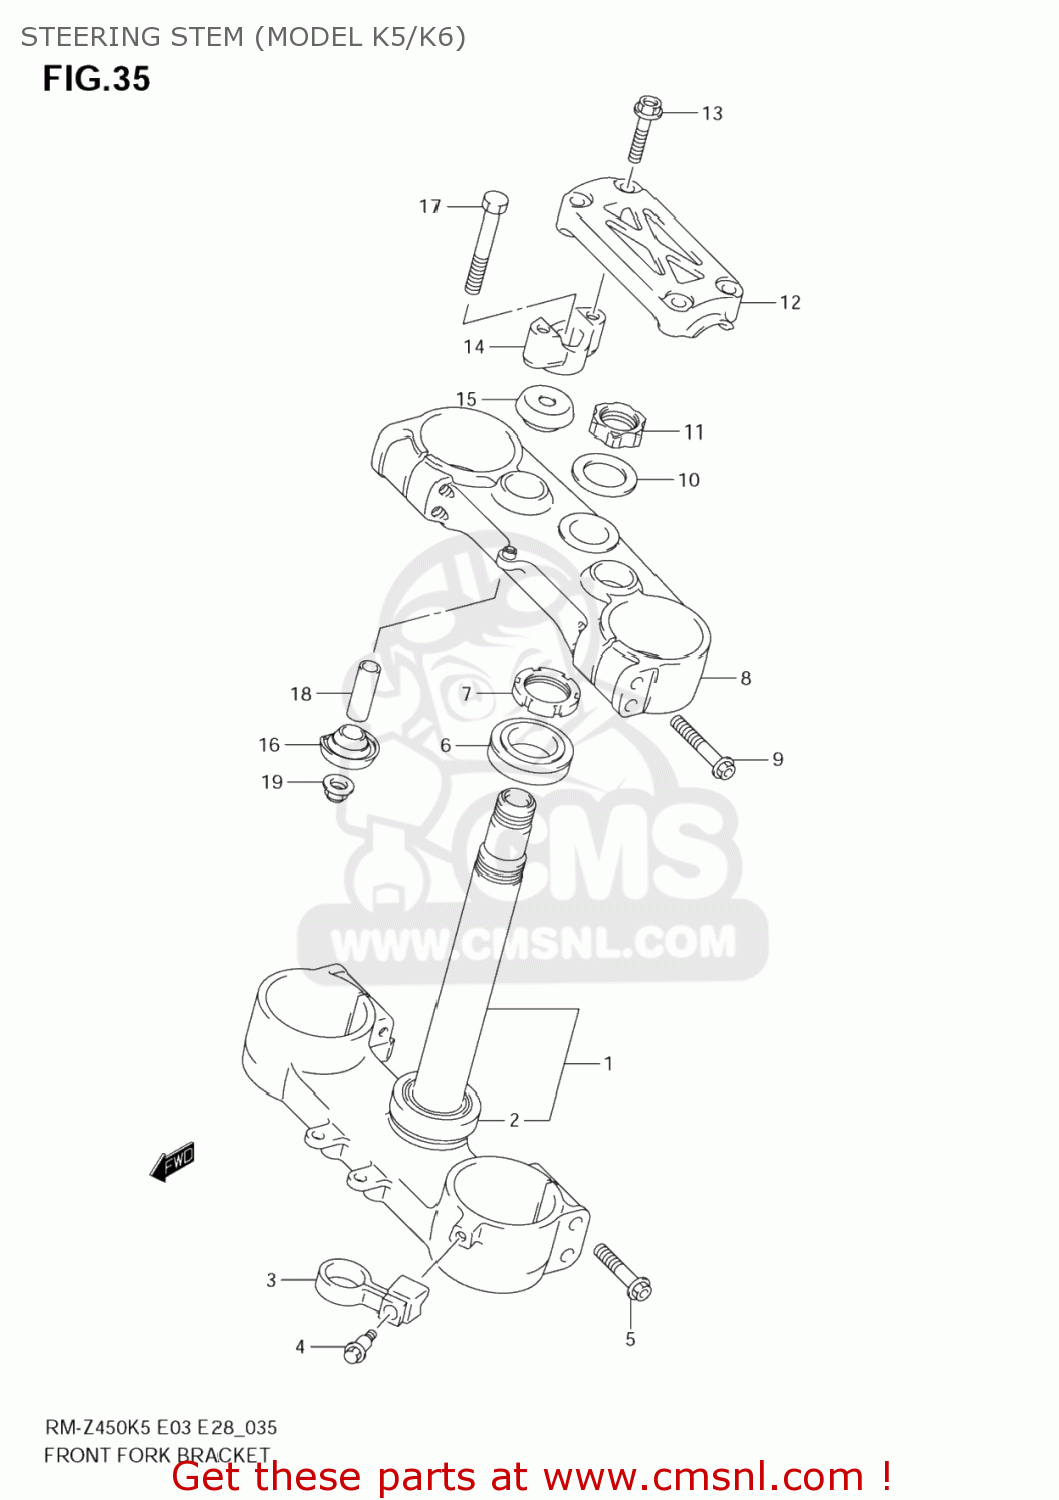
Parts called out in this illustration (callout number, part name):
1	STEM,STEERING
2	BEARING(30X52X16)
3	GUIDE,FR BRAKE HOSE
4	BOLT(6X20.5)
5	BOLT
6	BEARING(30X52X16)
7	NUT,STEERING
8	HEAD,STEERING STEM
9	BOLT
10	WASHER,STEM HEAD
11	NUT,STEM HEAD
12	HOLDER,HANDLE
13	BOLT
14	HOLDER,HANDLE LWR
15	CUSHION,RUBBER
16	CUSHION,RUBBER UNDER
17	BOLT
18	SPACER
19	NUT
